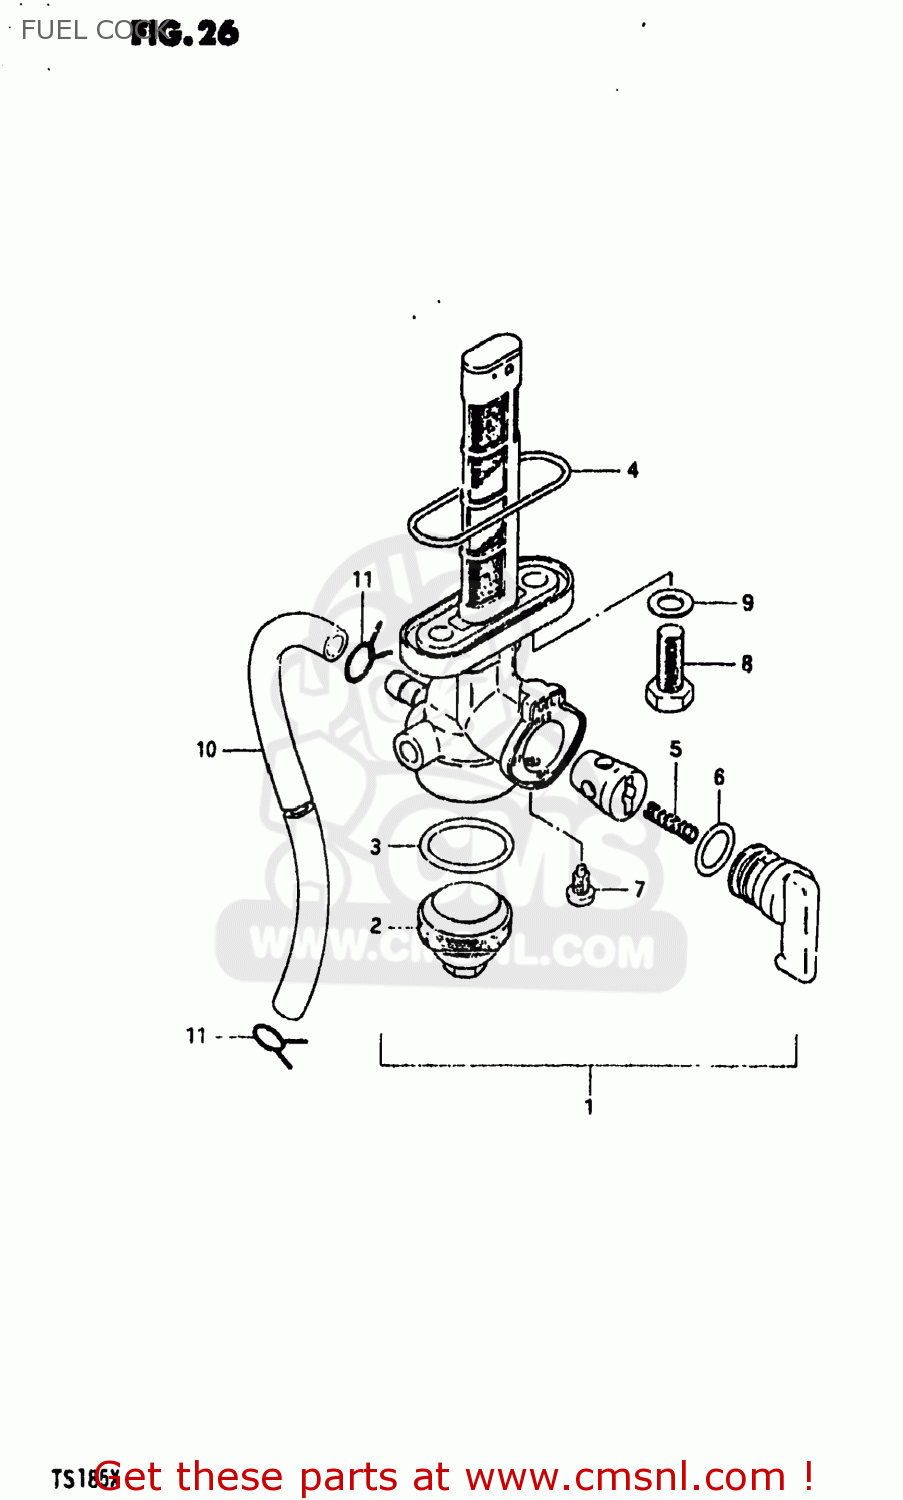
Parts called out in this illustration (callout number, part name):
1	COCK ASSEMBLY,FUEL
2	CUP,STRAINER
3	GASKET,FILTER (NAS)
4	GASKET,FILTER (NAS)
5	SPRING
6	O-RING
7	SCREW
8	BOLT(6X20)
9	GASKET
10	HOSE
11	CLIP
